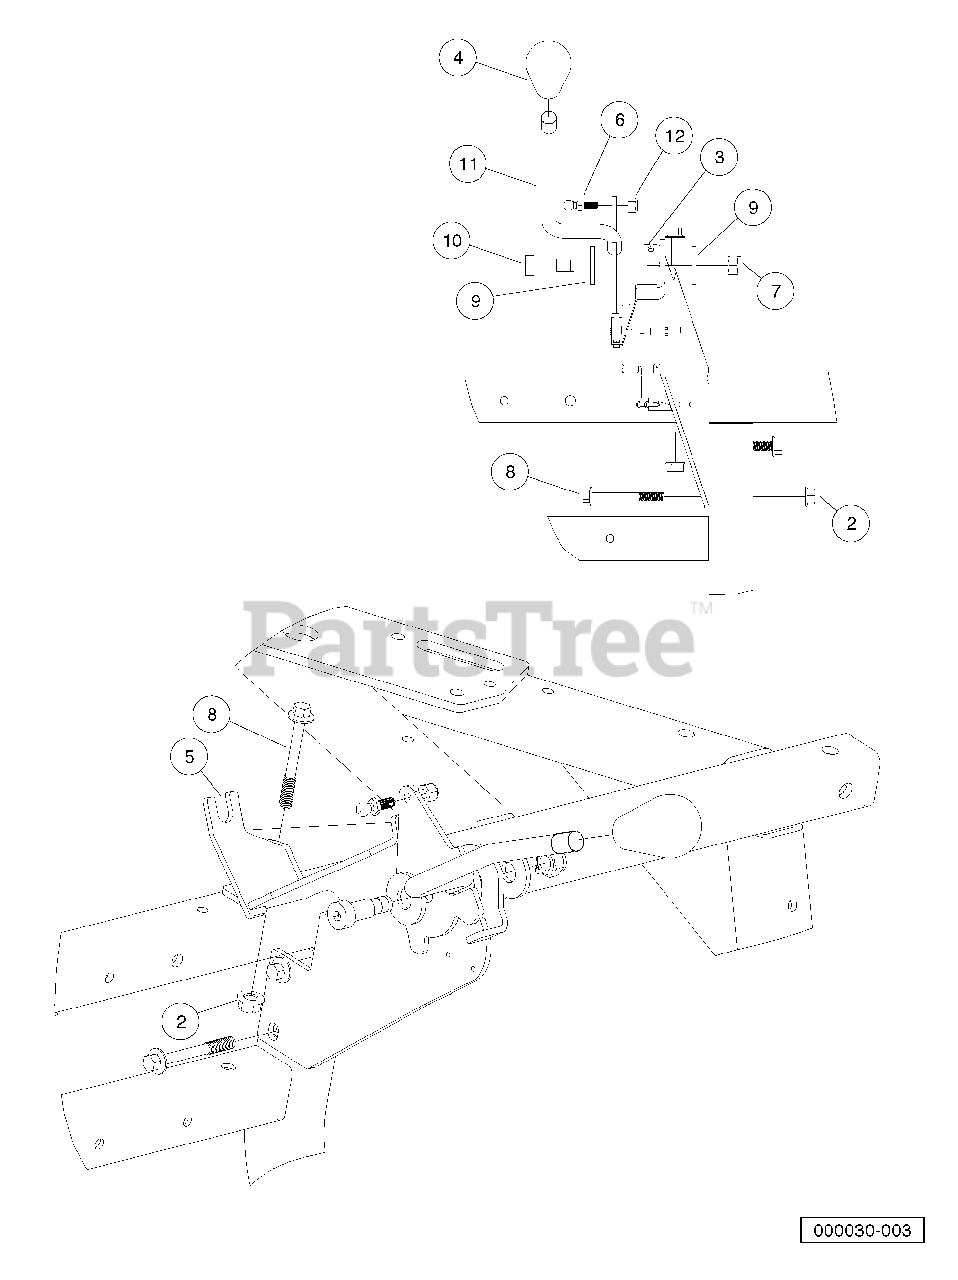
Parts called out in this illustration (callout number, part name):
1	Instl, Fnr, Shifter, Dom
2	Nut,m8,all Metal Lock
3	Bushing, Fnr
5	Weldment, FNR Shifter Bracket
6	Stud, Ball, .346 Dia
7	Locknut, M10x1.5 Nylon Insert
8	Bolt Flanged Head, M8 X 1.25 X 65
9	Washer, M12 Hard Regular
10	Shoulder Bolt,m12 X 20 M10 Thd
11	Weldment, FNR Shifter
12	Locknut, 1/4-28 Nylon Insert
13	Tie Wrap, 8" Nylon
